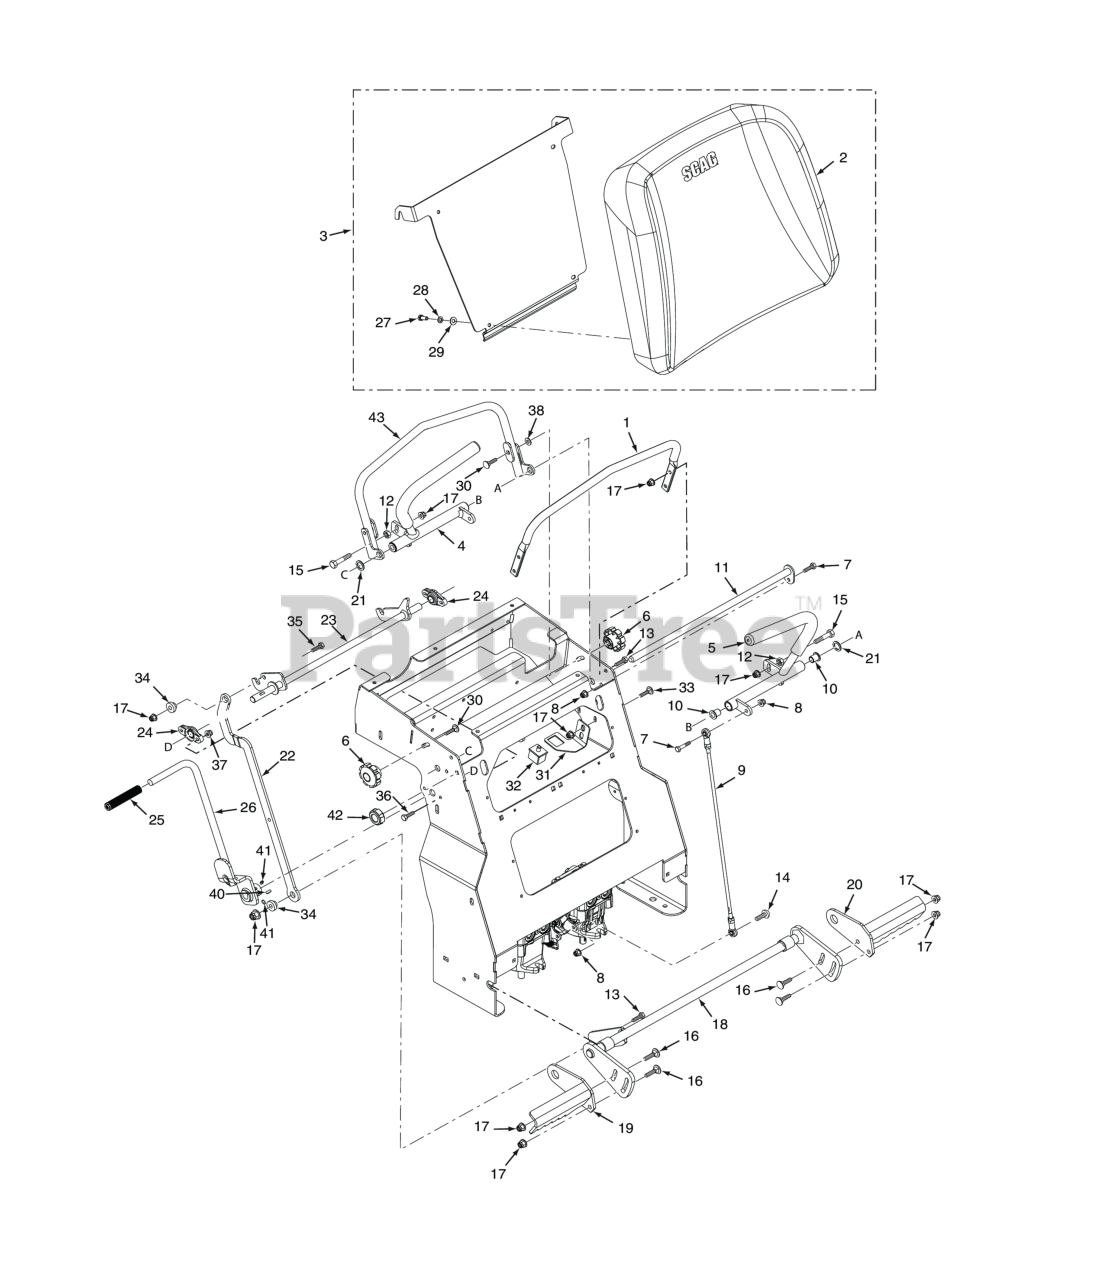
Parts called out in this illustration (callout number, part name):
1	Reference Bar
2	Operator Pad
3	Operator Pad Assy., w/Decal
4	Handlebar Assembly, LH
5	Handlebar Assembly, RH
6	Knob, 5/16 - 18
7	Bolt, Hex 5/16" - .375 x 1.00- Stainless Steel
8	Locknut, 5/16-18 Flg. Elastic Stop - Stainless Steel
9	Linkage Assy., Steering
10	Bearing, .625 ID Plastic
11	Shaft Weldment, Control Arm
12	Nut, 3/8 - 16 - Stainless Steel
13	Bolt, Hex Head 3/8 - 16 x 1.50 - Stainless Steel
14	Hex Head Socket, 5/16-18 x 1" (36)
15	Bolt, Hex 3/8 - 16 x 1.75 - Stainless Steel
16	Bolt, Carriage 3/8 - 16 x 1.25 - Stainless Steel
17	Nut, Flange Elastic Stop 3/8 - 16 - Stainless Steel
18	Bellcrank Weldment, Brake
19	BRAKE PADDLE WLMT, LH
20	Brake Paddle Weldment, RH
21	Washer, Flat 5/8 - .687 x 1.00 x .078 - Stainless Steel
22	Link, Brake Engage
23	Lock Weldment, Neutral
24	Bearing
25	GRIP, PARKING BRAKE
26	Brake Lever Assembly
27	Bolt, Hex 5/16 - 18 x .75 - Stainless Steel
28	Washer, Lock 5/16 Spring - Stainless Steel
29	Washer, Flat 5/16 - .349 x .750 x .050 - Stainless Steel
30	Bolt, Carriage 5/16 - 18 x 1" - - Stainless Steel
31	Mounting Bracket, Brake Switch
32	Switch, Double Pole - Plunger
33	Bolt, Carriage 3/8-16 x 1.0 - Stainless Steel
34	BUSHING, BRONZE - .376 ID X .627 OD
35	Cap Screw, 3/8 - 16 x 1.25 Hex Socket - Stainless Steel
36	Bolt, Hex 1/4 - 20 x 1.25 - Stainless Steel
37	Locknut, 1/4 - 20 Flg. Elastic Stop - Stainless Steel
38	Washer, Flat 5/16 - .349 x .750 x .050 - Stainless Steel
39	Nut, Push On - Stainless Steel
40	KEY, WOODRUFF #61, 3/16 X 5/8
41	Set Screw, 1/4 - 20 x .25 - Stainless Steel
42	Knob, 5/16-18
43	Weldment, Reference Bar
